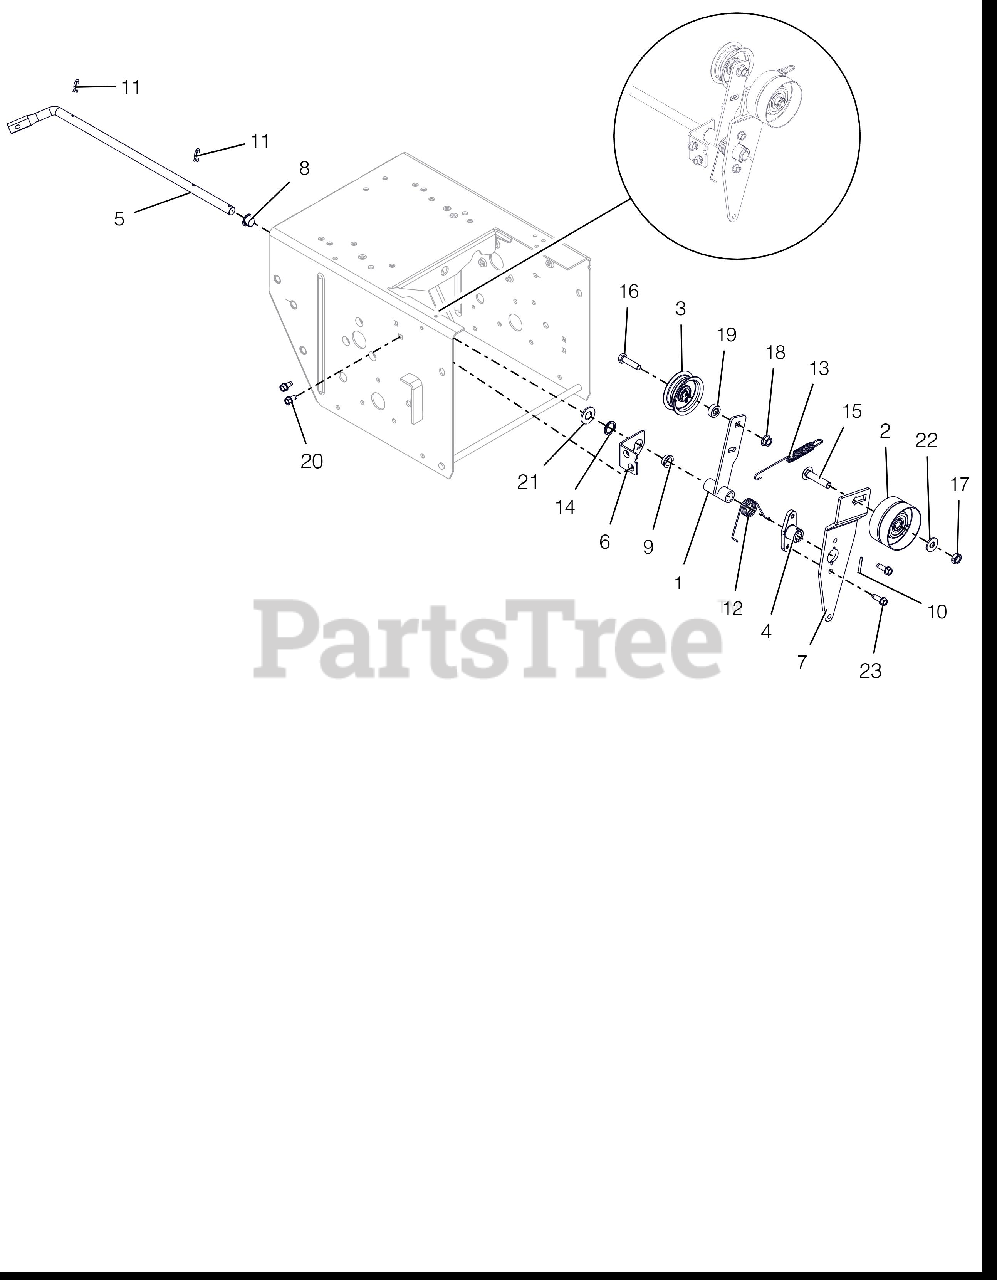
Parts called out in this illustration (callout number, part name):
1	ARM, IDLER-TRACTION
2	IDLER, FLAT-2.75 OD X .375 ID
3	IDLER, FLAT - 2.00"
4	HUB, BRAKE ARM
5	ARM, ATTACHMENT
6	BRACKET, SUPPORT
7	ARM, IDLER-ATTACHMENT
8	BUSHING, POLYLINER-.50 SPLIT
9	BSHG,FLANGE .500X.625X.270X.75
10	PIN-ROLL .125X1.00
11	CLIP, SPRING
12	SG-TORS .067X.88
13	SG-TENS .06X.482X5.35
14	WAVE SPRING .600X.875X.25FH
15	@BLT-RHDSSQNK .38-16X1.75 G5YZ
16	@BLT-HEX .31-18X1.25 GR5 YWZC
17	@NUT-LK-CTR-JAM .375-16 YWZC
18	@NUT-LK-TOP-FLG .31-18 YWZC
19	SPCR, BRG .315X.500X.358X.281
20	SCR-TAP .25-20X.50 HWH TR YWZ
21	@WSHR-FL-STL.531X1.06X.095YWZC
22	@WSHR-FL-STL.38X.875X.083 YWZC
23	SCR-TAP-PM .25-20X.75 TR YWZ
